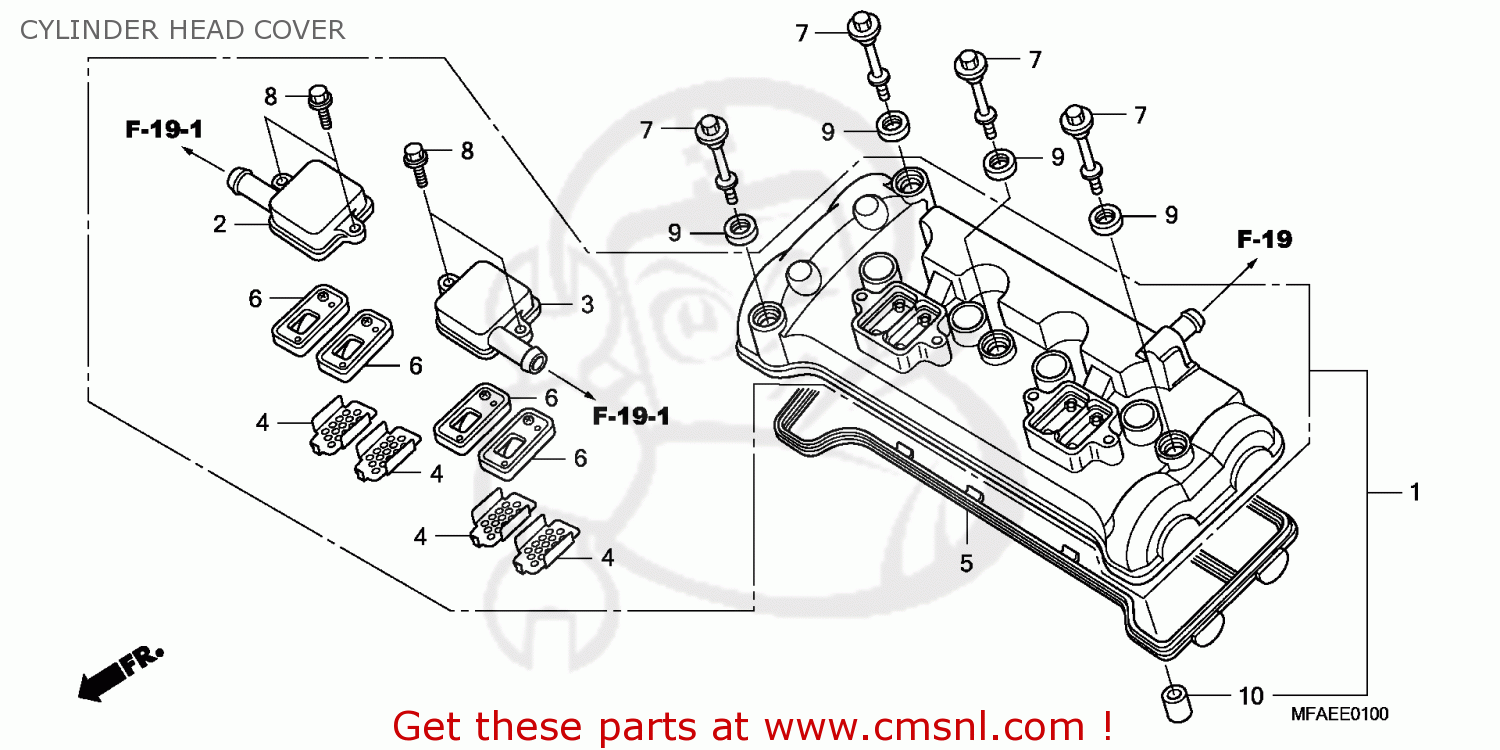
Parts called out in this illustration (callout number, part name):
1	COVER ASSY,CYLN H
2	COVER,R REED VALV
3	COVER,L REED VALV
4	PLATE,AI PORT
5	GASKET,HEAD COVER (NAS)
6	REED VALVE COMP
7	BOLT,HEAD COVER
8	BOLT,FLANGE,6X20
9	RUBBER,MOUNT
